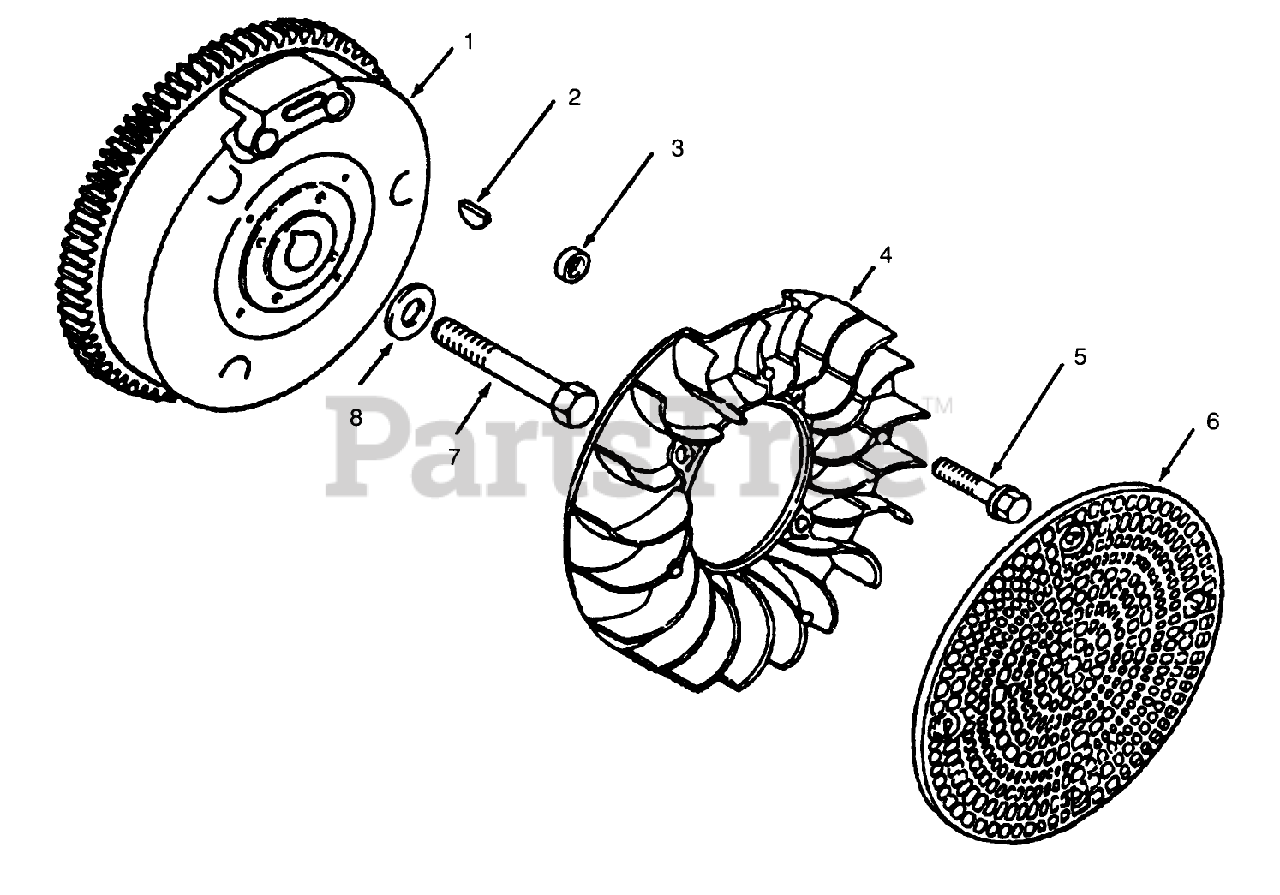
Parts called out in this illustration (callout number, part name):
1	KOHLER 47-025-53
2	KOHLER X-46-3
3	KOHLER 41-100-01
4	KOHLER 25-157-01
5	KOHLER 25-086-21
6	KOHLER 25-162-01
7	KOHLER 25-086-24
8	KOHLER 52-468-15
